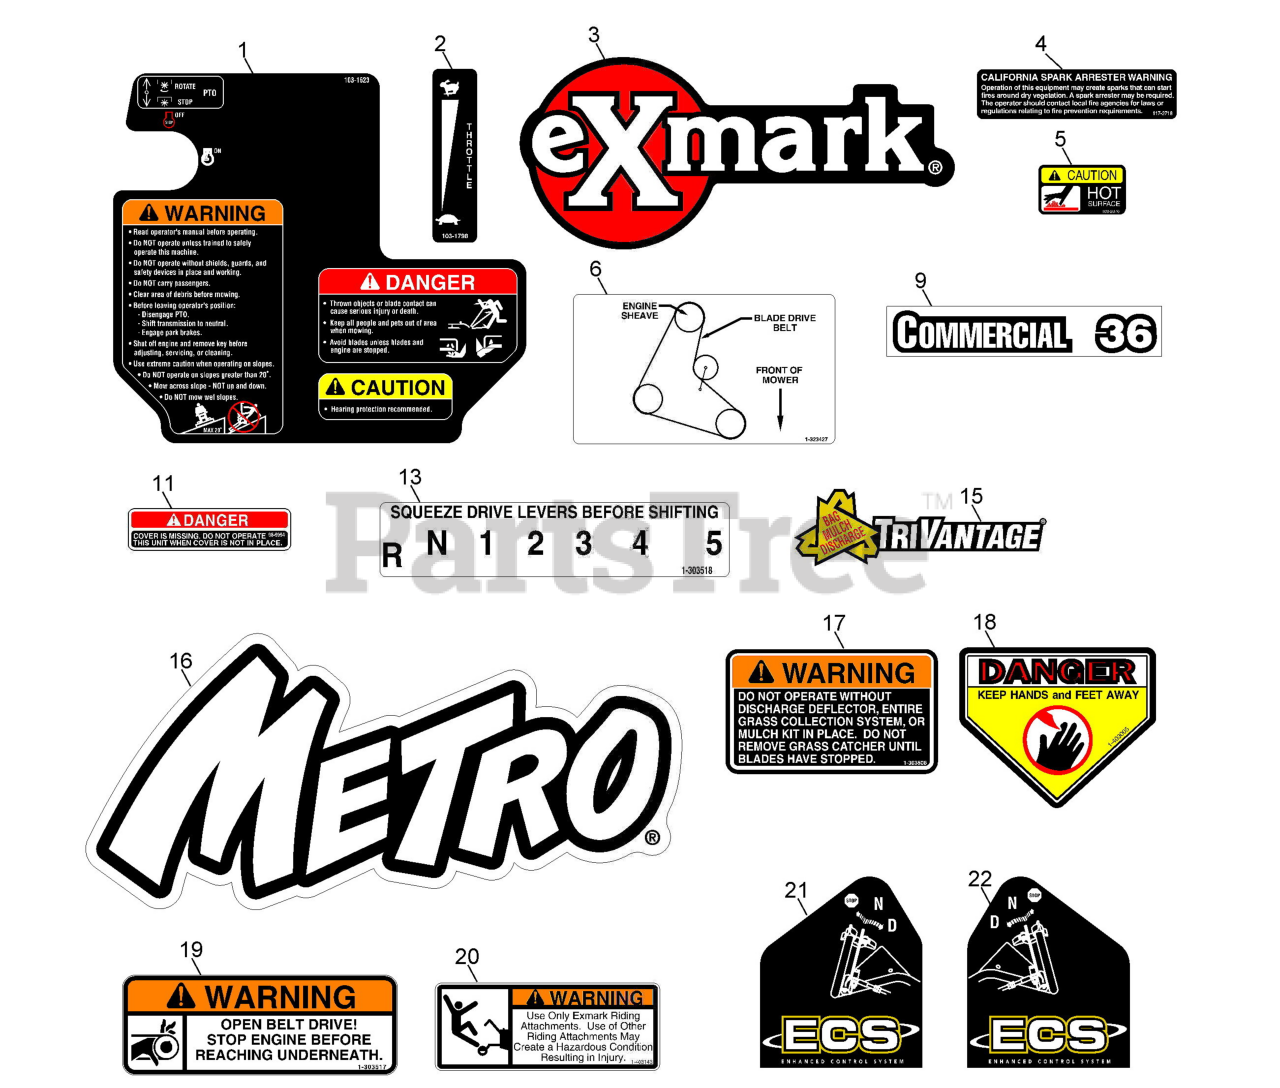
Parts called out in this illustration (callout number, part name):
1	DECAL,METRO ECS CONSOLE
2	DECAL,THROTTLE ONLY
3	DECAL,EXMARK LOGO
4	DECAL-ARRESTER, SPARK
5	DECAL-CAUTION
6	DECAL,BELT ROUTING 32/36
9	DECAL,COMMERCIAL 36
11	DECAL-COVER, MISSING
13	DECAL,SHIFTER
16	DECAL,METRO MODEL
17	DECAL-WARNING, DISCHARGE
18	DECAL-DANGER
19	DECAL,BELT DRIVE
20	DECAL,SULKY WARNING
21	DECAL,RH ECS INSTRUCTION
22	DECAL,LH ECS INSTRUCTION
